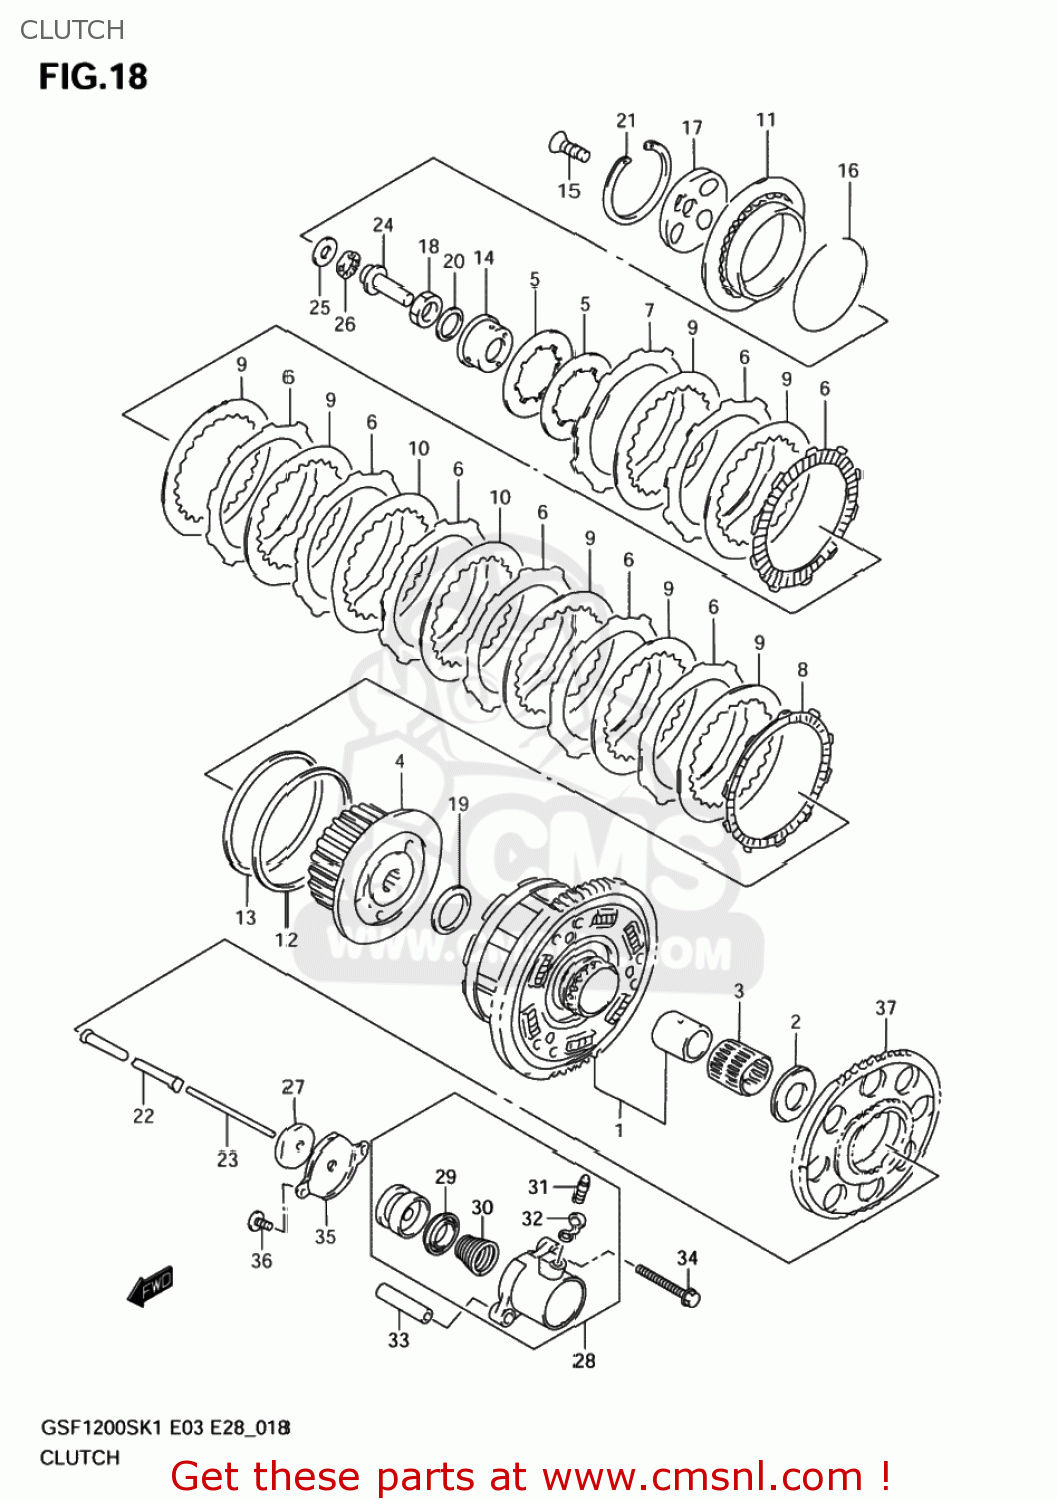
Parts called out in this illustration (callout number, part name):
1	GEAR ASSY,PRI DRIVEN
2	WASHER(25X54X2.5)
3	BEARING(35X40X35.8)
4	HUB,CLUTCH SLEEVE
5	WASHER
6	PLATE,CLUTCH DRIVE NO.1 (NAS)
7	PLATE,CLUTCH DRIVE (NAS)
8	PLATE,CLUTCH DRIVE (NAS)
9	PLATE,CLUTCH DRIVEN NO.1
10	PLATE,CLUTCH DRIVEN NO.2
11	DISC,CLUTCH PRESSURE
12	SEAT,CLUTCH PLATE WAVE WASHER
13	WASHER,CLUTCH PLATE WAVE
14	HOLDER,CLUTCH SPRING
15	SCREW,CLUTCH SPRING HOLDER
16	SEAT,CLUTCH SPRING
17	LIFTER,CLUTCH PRESSURE DISC
18	NUT
19	WASHER(25X50X2.5)
20	WASHER
21	CIRCLIP
22	ROD,CLUTCH PUSH,R
23	ROD,CLUTCH PUSH,L
24	PIECE,CLUTCH PUSH
25	WASHER(15.5X28X1)
26	BEARING(15X28X2)
27	SEAL,OIL(6X34X5.5)
28	CYLINDER,CLUTCH RELEASE
29	CUP,CLUTCH CYLINDER
30	SPRING,CLUTCH CYLINDER
31	BLEEDER
32	CAP,BLEEDER
33	PIN
34	BOLT(6X25)
35	COVER,CLUTCH RELEASE CYLINDER
36	SCREW
37	GEAR,GENERATOR DRIVE
